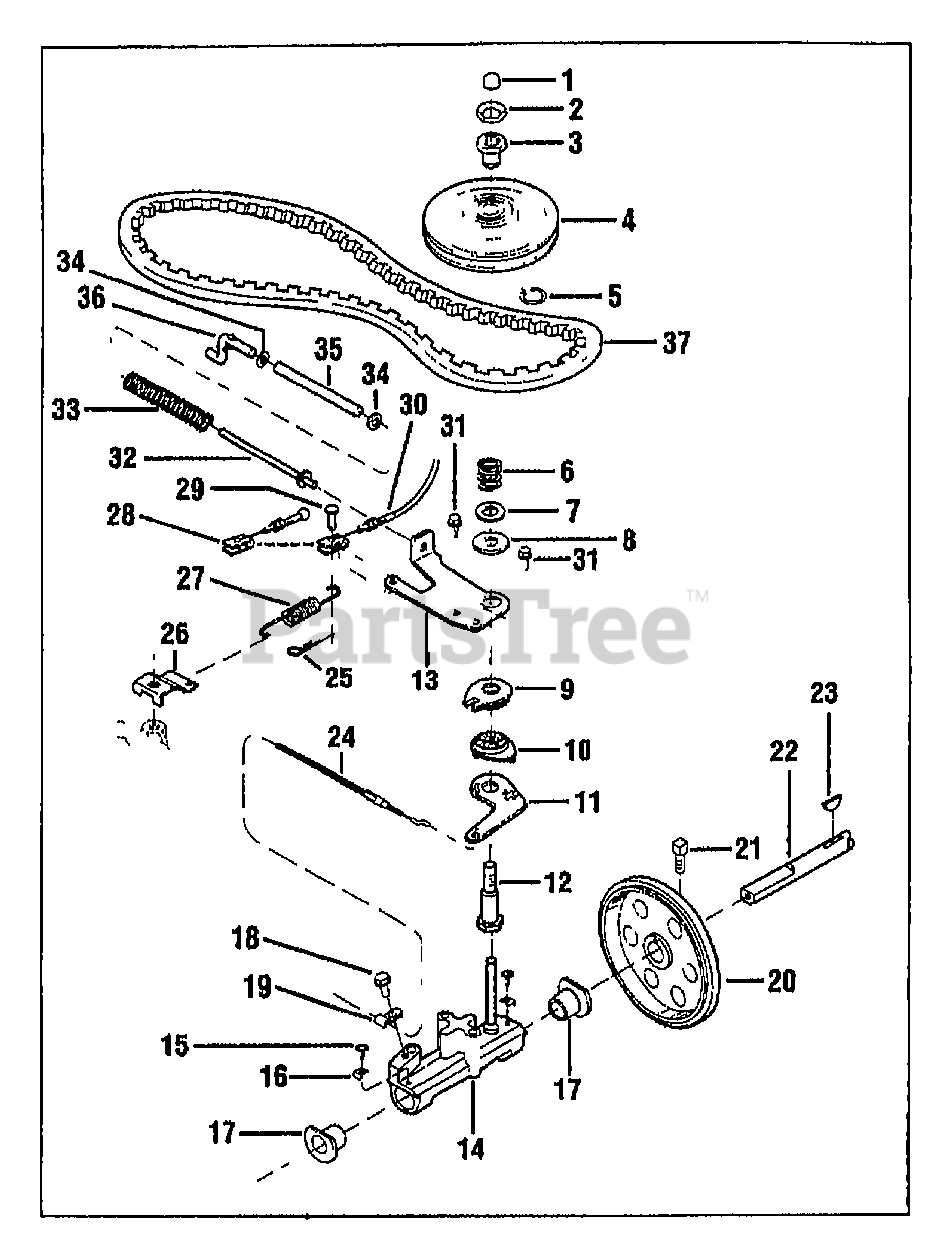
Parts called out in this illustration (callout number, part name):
2	NUT-H/LK 1/2-20
3	NUT-HEX 1/2-20X.5
4	ASSM-SHEAVE W/BEARING
5	RING-RETAINING (SNAP)
6	SPRING-COMPRESSION
7	WASHER-1.0X.632X.03 ZP
8	WASHER-.605X1.102X.08
9	PLATE-RAMP UPPER
10	PLATE-RAMP LOWER
11	ARM-CONTROL
12	SLEEVE-ADJUST
13	PLATE-ANCHOR PLATED
14	ASSM-CARRIER W/STUD
15	SCR-TORX HD
16	CLIP-BRG RETAIN BLK OXIDE
17	BEARING-CARRIER
18	SCR-HW M10-24 THRFRM
19	CLAMP-HOUSING
20	DISC-DRIVE/FRICTION
21	SCR-SET SQ 1/4-20 W/NYLOC
22	AXLE-DRIVE ROUND NGMM
23	KEY-WOODRUFF .125X.5
24	CABLE-DRIVE CONTROL
25	PIN-CLIP .08
27	SPRING-SPEED CONTROL
28	CABLE-SINGLE SPD CONTROL {34021}
29	PIN-SPEED CONTROL
30	ASSM-ARM CONTROL {NOT 34020,34021}
31	SCR-FLANGE 1/4-20X3/4 GR5
32	ROD-BELT ADJ
33	SPRING-COMPRESSION
34	WASHER-FLAT 1/4 SAE
35	SLEEVE-BELT
36	KIT-SVC ANCHOR Z ROD
37	BELT-V NGMM
